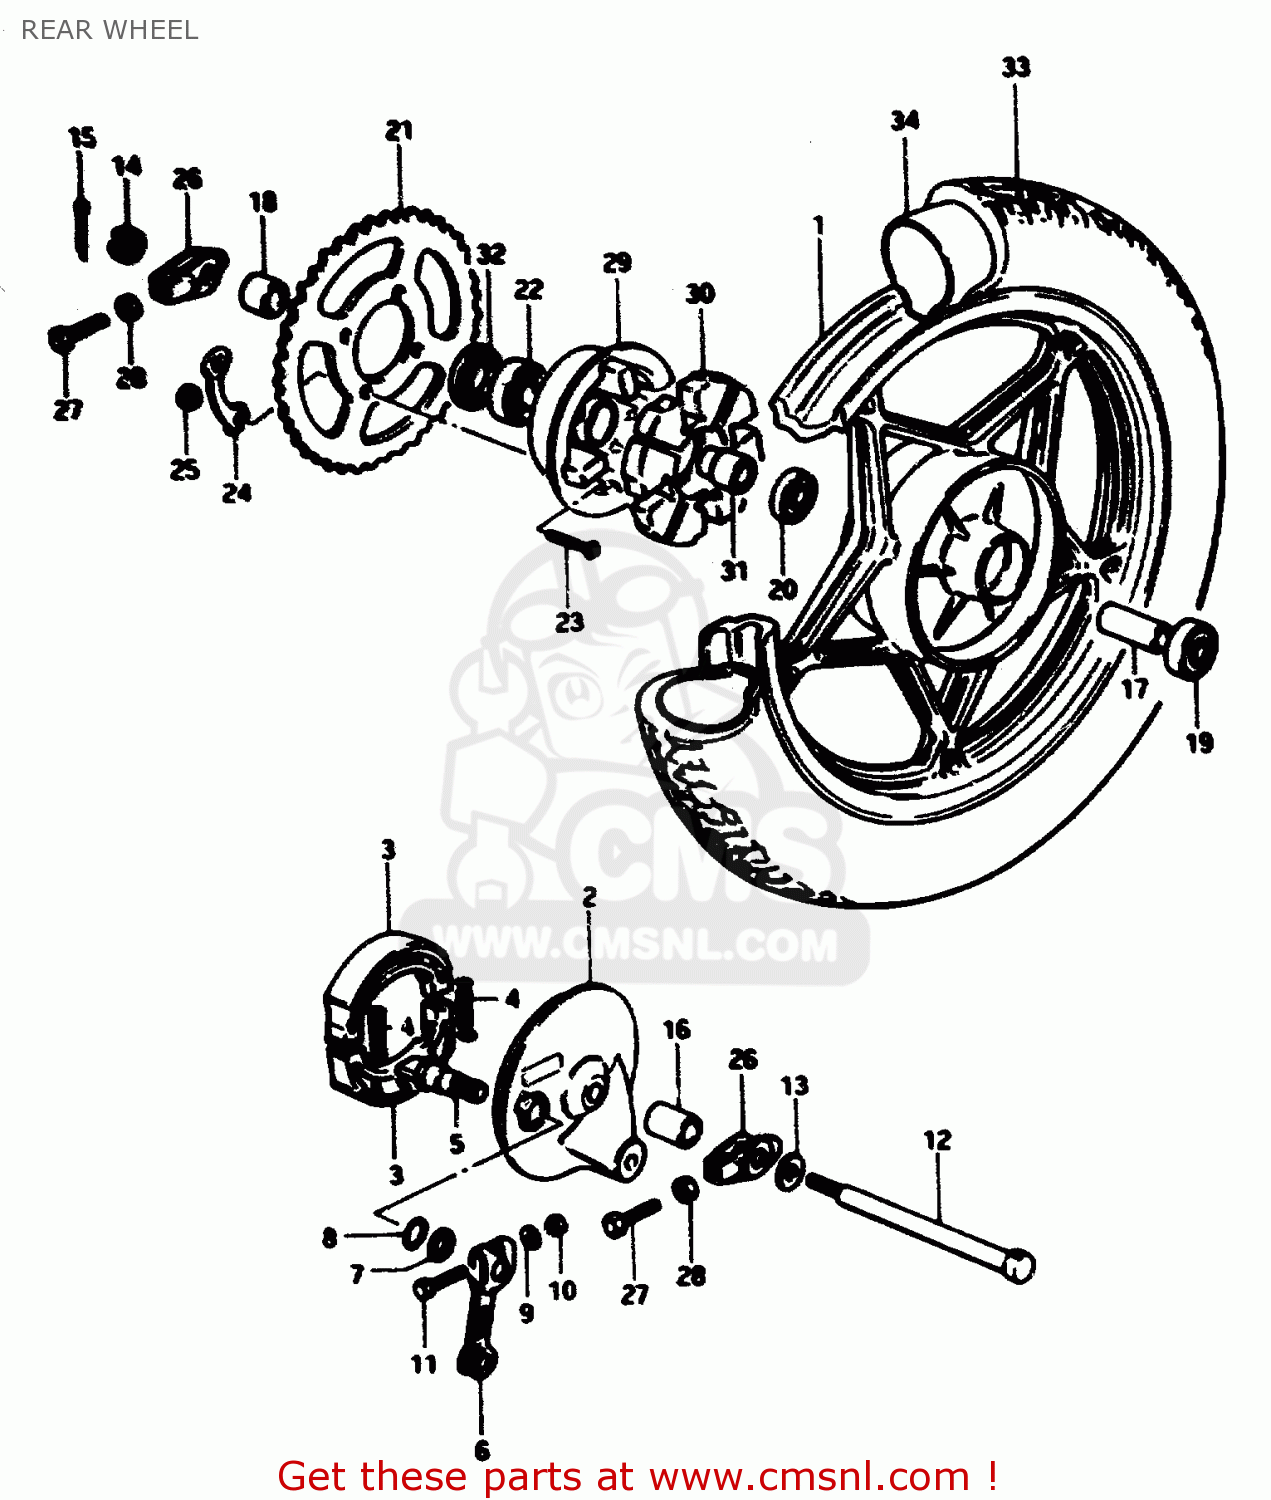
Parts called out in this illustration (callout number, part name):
1	WHEEL, REAR (185X16)
2	PANEL, REAR HUB
3	SHOE,BRAKE (MCA)
4	SPRING(L:34)
5	CAM,FRONT BRAKE
6	LEVER, BRAKE CAM
7	WASHER (14.5X22X1.6)
8	O-RING (D:2.4 ID:13.8)
9	WASHER
10	NUT
11	BOLT(6X33)
12	AXLE,FRONT
13	WASHER
14	NUT 12MM
15	COTTER PIN
16	SPACER, AXLE RH
17	SPACER (12.6X19X58)
18	SPACER 12X25X2
19	BEARING
20	BEARING
21	SPROCKET,REAR
22	BEARING
23	BOLT(8X33.5)
24	WASHER
25	NUT
26	27
27	BOLT(6X38)
28	NUT
29	DRUM,RR SPROCKET MOUNTING
30	ABSORBER,RR HUB SHOCK
31	RETAINER,RR SPROCKET DRUM
32	SEAL OIL(25X40X6)
33	TIRE (3.25-16)
34	TUBE
